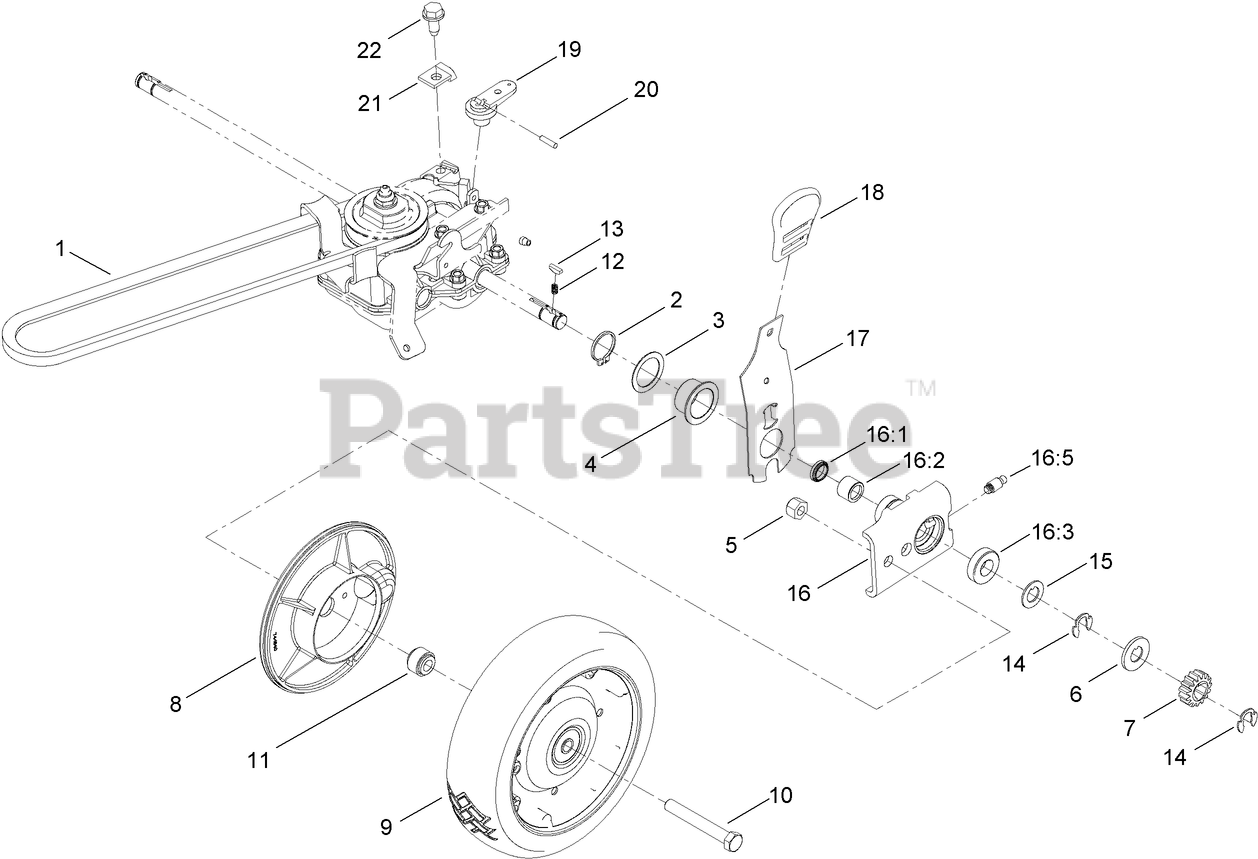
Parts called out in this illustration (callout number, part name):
1	V-BELT
2	RING-RETAINING
3	WASHER
4	BUSHING-FLANGE
5	NUT-LOCK, CONE
6	WASHER-THRUST, OUTER
7	GEAR-PINION
8	COVER-WHEEL
9	WHEEL AND TIRE ASM
10	SCREW-HH
11	SPACER-COVER, WHEEL
12	SPRING-COMPRESSION
14	RING-RETAINING
15	WASHER-THRUST, OUTER
16	PIVOT ARM ASM
16:1	SEAL-OIL
16:2	BEARING-ROLLER
16:3	BEARING-WHEEL
17	REAR SPRING ARM ASM
18	KNOB-HOC
19	LEVER-SHIFT
20	PIN-COIL
21	CLAMP-CABLE
22	SCREW-HWHTF
